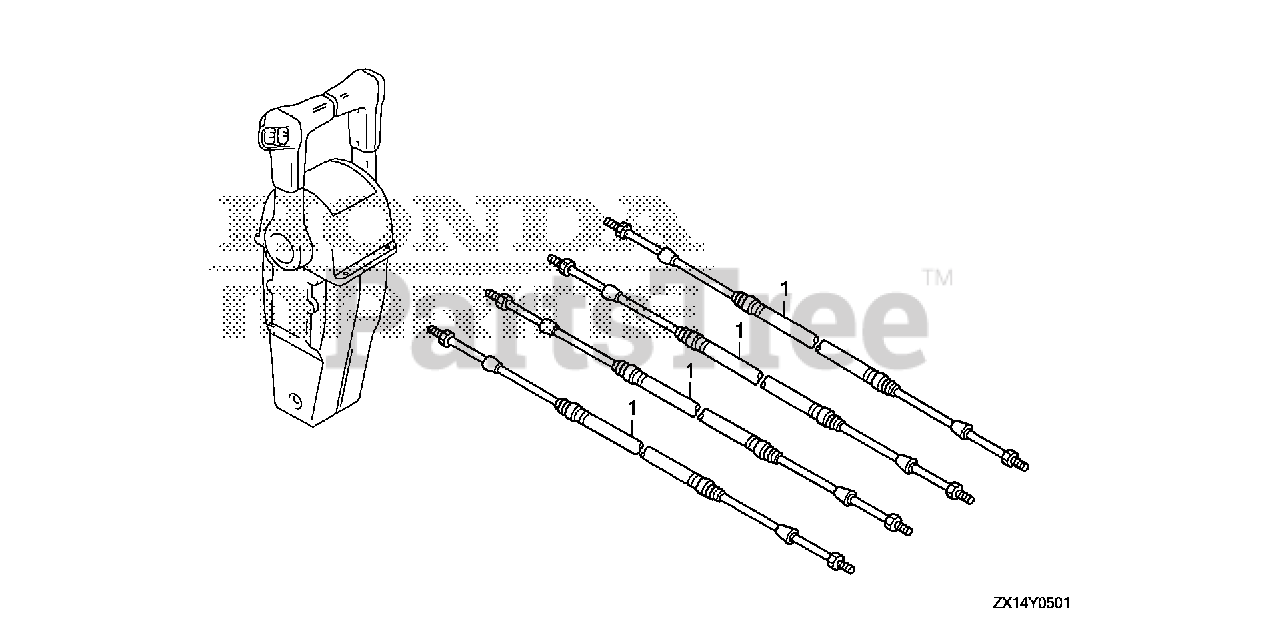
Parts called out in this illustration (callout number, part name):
1	CABLE ASSY., PUSH-PULL (33C-5FT)
1	CABLE ASSY., PUSH-PULL (33C-6FT)
1	CABLE ASSY., PUSH-PULL (33C-7FT)
1	CABLE ASSY., PUSH-PULL (33C-8FT)
1	CABLE ASSY., PUSH-PULL (33C-9F T)
1	CABLE ASSY., PUSH-PULL (33C-10FT)
1	CABLE ASSY., PUSH-PULL (33C-11FT)
1	CABLE ASSY., PUSH-PULL (33C-12 FT)
1	CABLE ASSY., PUSH-PULL (33C-13 FT)
1	CABLE ASSY., PUSH-PULL (33C-14FT)
1	CABLE ASSY., PUSH-PULL (33C-15 FT)
1	CABLE ASSY., PUSH-PULL (33C-16FT)
1	CABLE ASSY., PUSH-PULL (33C-17 FT)
1	CABLE ASSY., PUSH-PULL (33C-18 FT)
1	CABLE ASSY., PUSH-PULL (33C-19FT)
1	CABLE ASSY., PUSH-PULL (33C-20FT)
1	CABLE ASSY., PUSH-PULL (33C-21FT)
1	CABLE ASSY., PUSH-PULL (33C-22FT)
1	CABLE ASSY., PUSH-PULL (33C-23FT)
1	CABLE ASSY., PUSH-PULL (33C-24FT)
1	CABLE ASSY., PUSH-PULL (33C-25FT)
1	CABLE ASSY., PUSH-PULL (33C-26FT)
1	CABLE ASSY., PUSH-PULL (33C-27FT)
1	CABLE ASSY., PUSH-PULL (33C-28FT)
1	CABLE ASSY., PUSH-PULL (33C-29FT)
1	CABLE ASSY., PUSH-PULL (33C-30FT)
1	CABLE ASSY., PUSH-PULL (33C-31FT)
1	CABLE ASSY., PUSH-PULL (33C-32FT)
